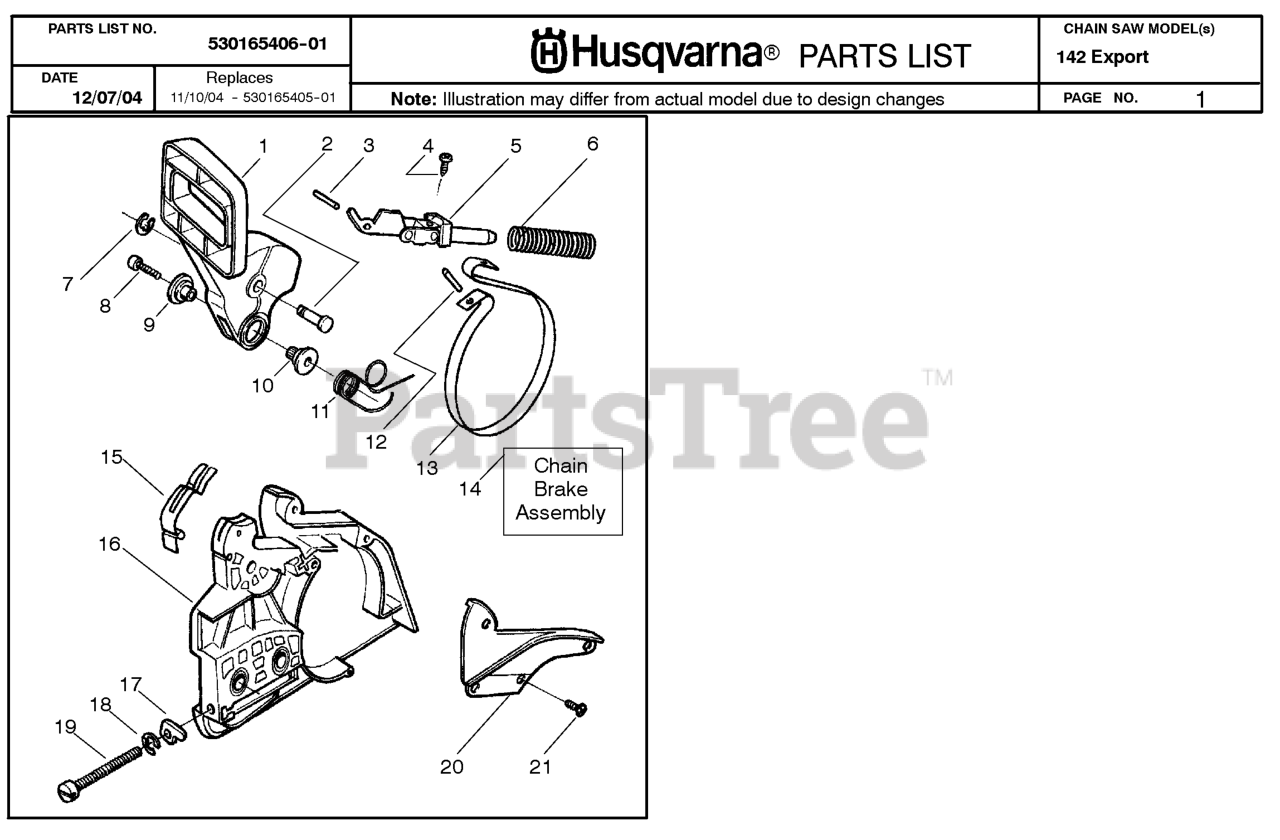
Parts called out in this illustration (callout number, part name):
2	LABEL
3	DECAL
4	DECAL 80 DBA
6	DECAL
7	DECAL.HOOD.LOGO.ORANGE.HUSQVAR
8	DECAL
10	DECAL BTRY SYMBOLS
11	DECAL.INTERNATIONL.CUTFINGER
16	DECAL
17	DECAL PARK BRAKE
